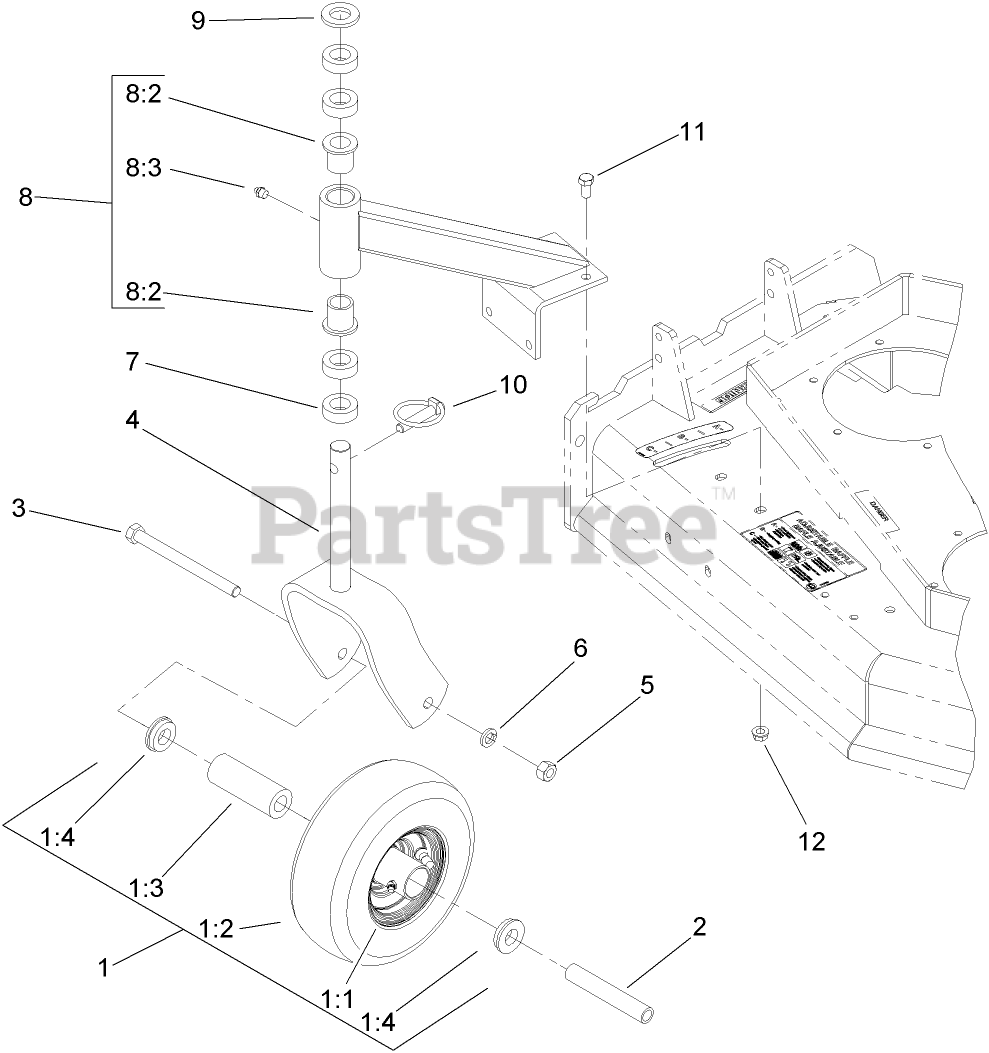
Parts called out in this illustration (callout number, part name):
1	WHEEL AND TIRE ASM
1:1	Rim
1:3	BEARING
1:4	BUSHING
2	SPACER
3	SCREW-HH
4	FORK
5	NUT-HH
6	WASHER-LOCK
7	SPACER-CASTER
8	SUPPORT ASM
8:2	BEARING-FLANGED
8:3	FITTING-GREASE
9	WASHER-FLAT
11	SCREW-HH
12	NUT-HHF, WHIZ
